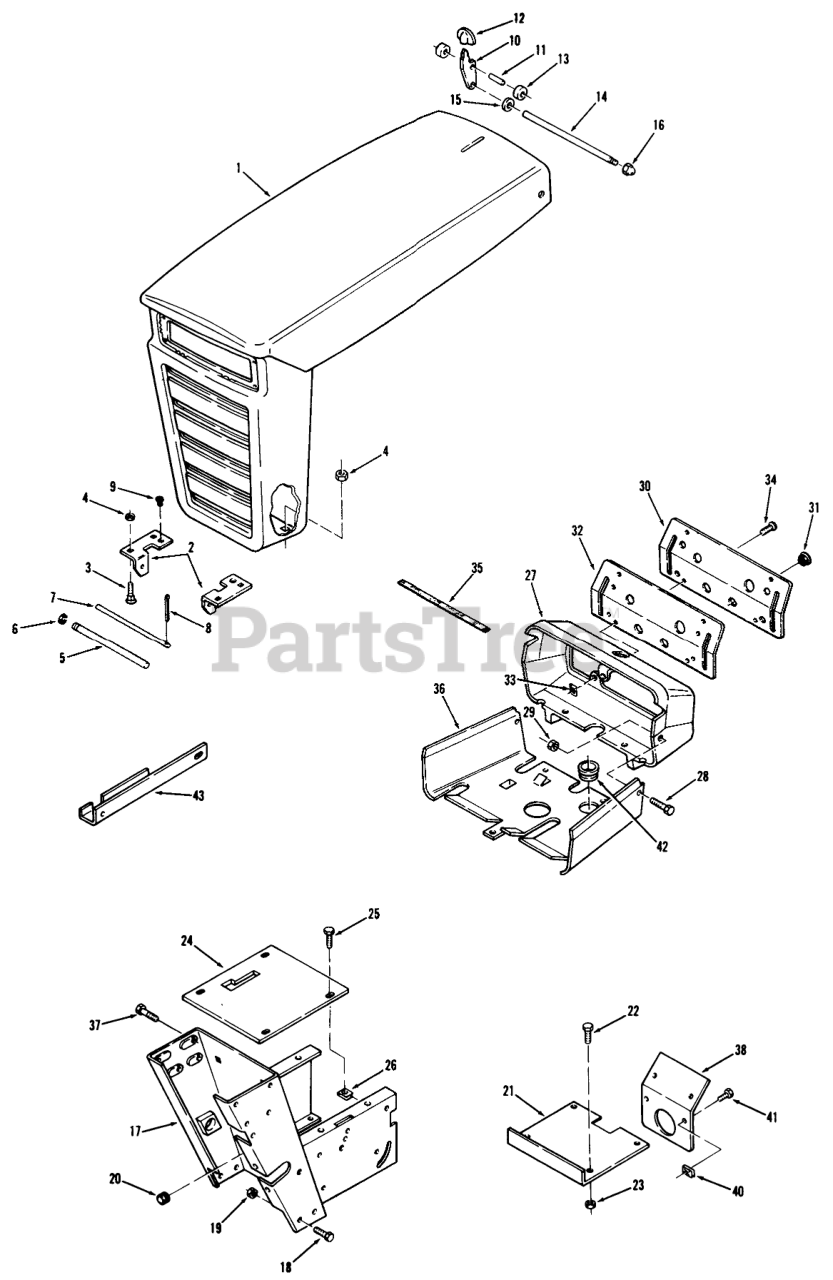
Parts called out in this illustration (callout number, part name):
1	Hood
2	Bracket-Grille-L.H.
2	GRILL PIVOT BRKT
3	Bolt
4	Nut
5	GRILL PIVOT ROD
6	RING-RETAINING
7	ROD-HOOD STOP
8	Cotter Pin
9	GROMMET
10	LEVER HOOD LATCH
11	SPIROL PIN
12	KNOB
13	Roller
14	Rod Latch
15	SPEED NUT
17	Assy-Hoodstand
18	BOLT
19	Nut
20	Bushing
21	Cover-Dust
22	Bolt
23	Nut
24	Plate
25	Screw
26	Speed Nut
27	Housing
28	Screw
30	Dash Panel
31	PLUG BUTTON
32	BACK UP PLATE
33	SPEED NUT
34	SCREW BLACK
35	Tape
36	Support-Tank
37	Screw
38	Instrument Backet
40	Speed Nut
41	Screw
42	Grommet
43	Channel
